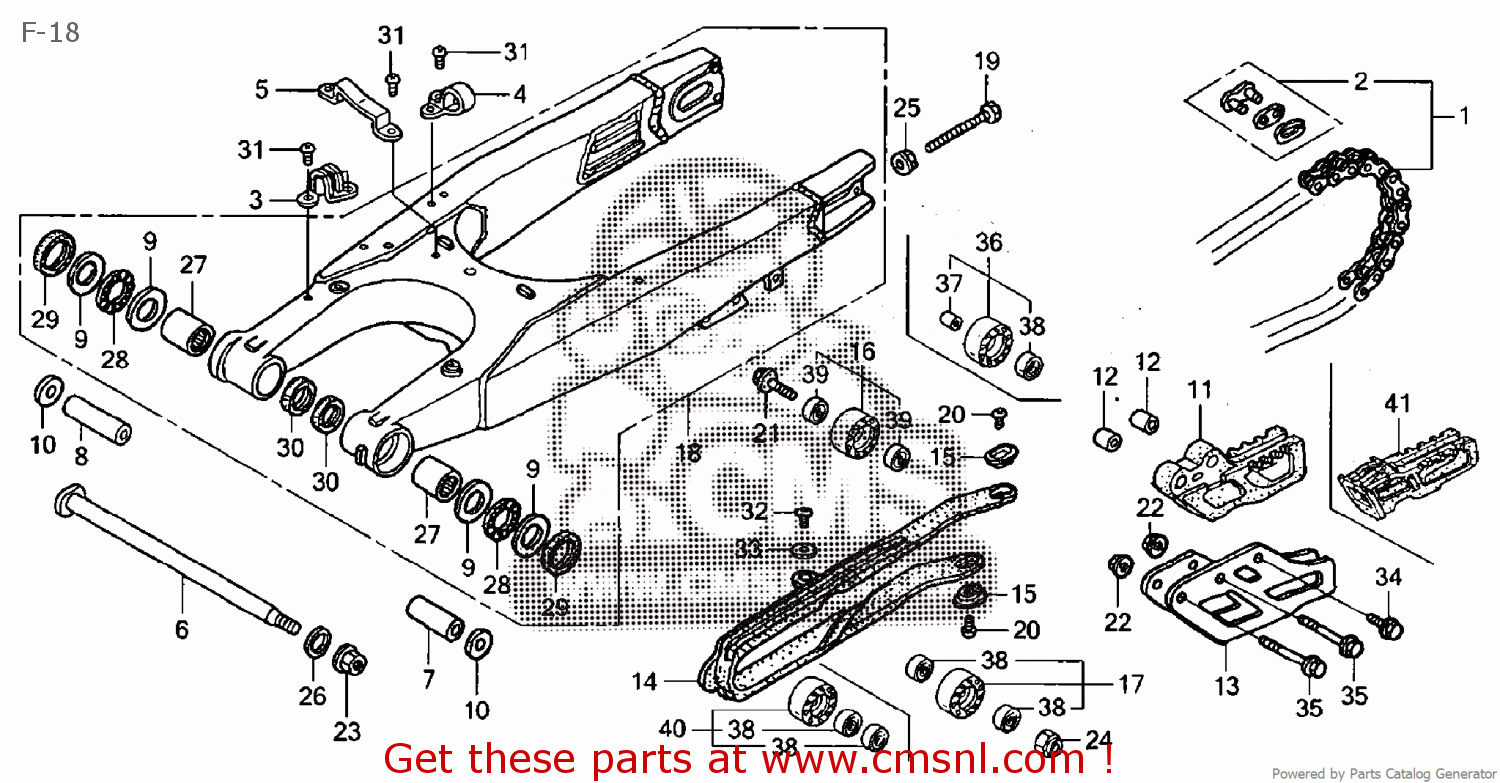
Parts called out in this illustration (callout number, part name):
1	CHAIN,DRIVE,DID52
2	JOINT RJ,DRIVE CH
3	GUIDE,BRK HOSE
4	GUIDE,BRK HOSE
5	GUIDE,BRK HOSE
6	SHAFT,SWINGARM PI
7	COLLAR,SWINGARM 4
8	COLLAR,SWINGARM 5
9	WASHER,SWINGARM S
10	SIDE COLLAR,SWING
13	PLATE,CHAIN GUIDE
14	SLIDER,CHAIN
15	WASH.,CHAIN SLIDE
18	SWINGARM SUB ASSY
19	BOLT,HEX.8X47.5
20	SCREW,PAN,5X8
21	BOLT,SH DR 8X32
22	NUT,U.,6MM
23	NUT,HEX,U 14MM
24	NUT,U.,6MM
25	NUT,HEX.,8MM
26	WASHER,14MM
27	NEEDLE BRG
28	BEARING,NEEDLE TH
29	DUST SEAL,30X37X4
30	DUST SEAL 22X29X4
31	SCREW,CROSS 5X8
32	SCREW CROSS 5X8
33	WASHER,PLAIN,5MM
34	BOLT,FLANGE,6X12
35	BOLT,FLANGE,6X45
36	ROLLER COMP,CHAIN
37	COLLAR,CHAIN TENS
38	BRG BALL RADIAL(6
40	ROLLER COMP,CHAIN
41	GUIDE,CHAIN
